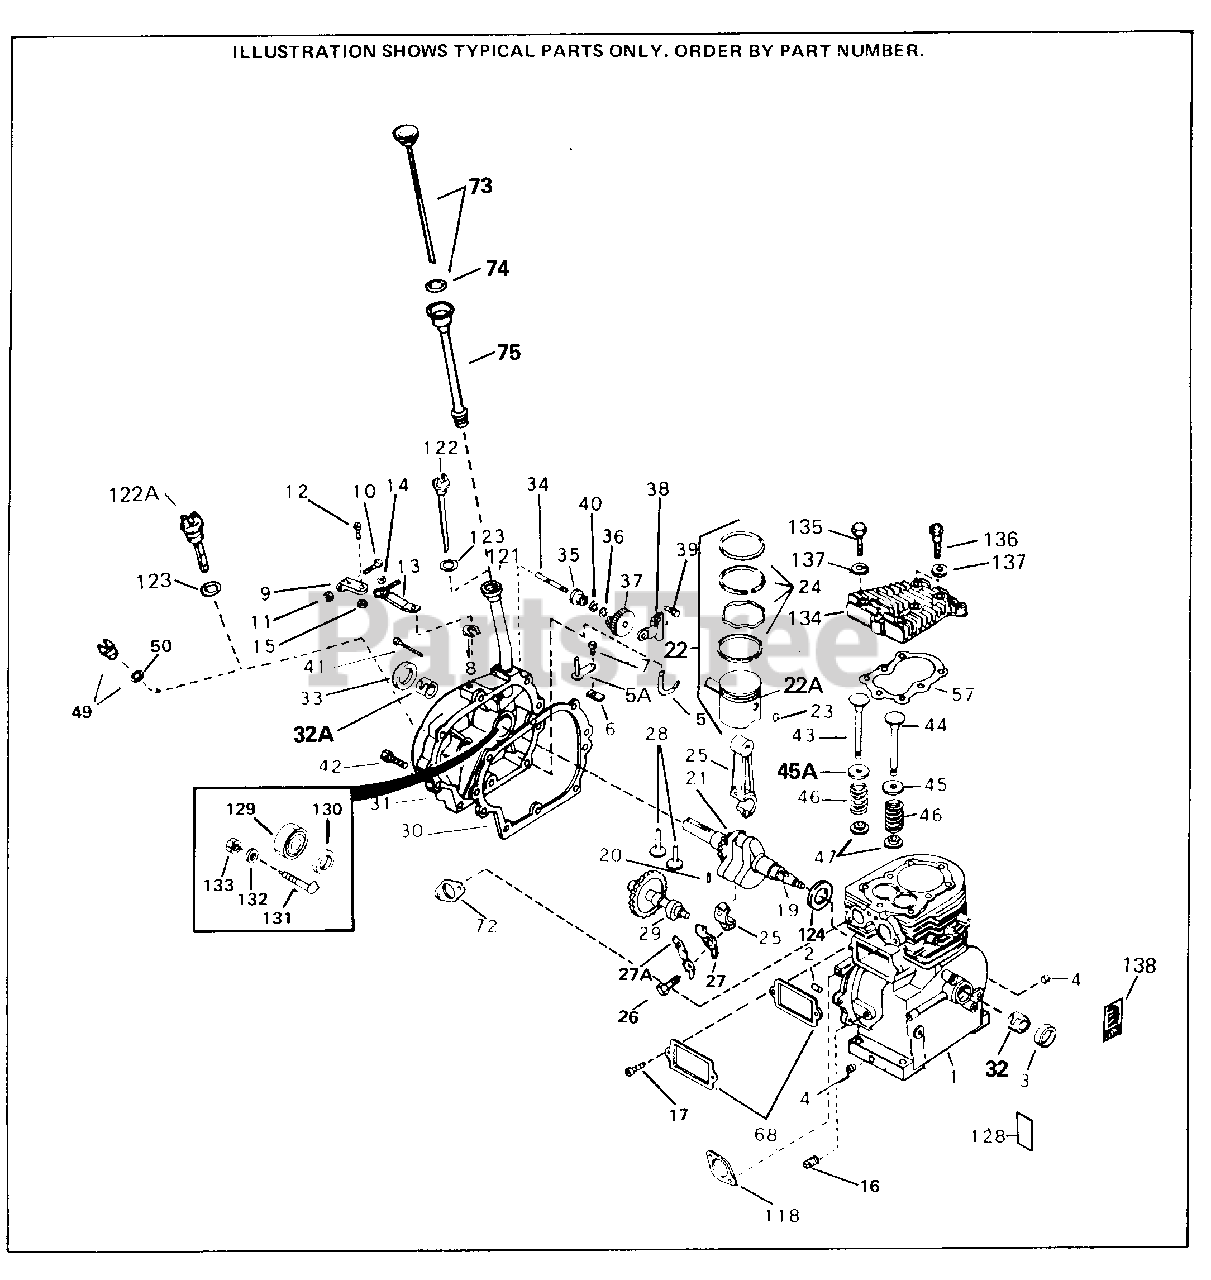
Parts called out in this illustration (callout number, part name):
1	"Cylinder (Incl. 2,3,4,16)(3-5/16") CI liner
2	Dowel Pin
3	Seal, Oil
4	Oil Drain Plug (Sq. hd., 1/4-18)
5	Rod Assy., Governor This one piece go vernor rod is no longer used. It is r eplaced by No. 30699C assy., Ref. 5A
5A	Rod Assy., Governor (Incl. 6 & 7)
6	Yoke, Governor
7	Screw, 6-40 x 5/16"
8	Retaining Ring
9	Governor Lever Clamp
10	Screw, 10-32 x 3/4"
11	Lock Nut, 10-32
12	Screw, 8-32 x 5/16"
13	Lever, Governor
14	Lock Washer #8
15	Lock Nut, 8-32
16	Plug, Pipe
17	Screw, 10-24 x 1/2" (Use as required)
19	Crankshaft
20	Pin, Crankshaft gear only)
21	Crankshaft Gear Early production onl y
22	Piston, Pin & Ring Set (Std.)
22	Piston, Pin & Ring Set (.010" OS)
22	Piston, Pin & Ring Set (.020" OS)
22A	Piston & Pin Ass'y. (Std.)(3-5/16") I ncl. 23
22A	Piston & Pin Ass'y. (.010" OS) Incl. 23
22A	Piston & Pin Ass'y. (.020" OS) Incl. 23
23	Piston Pin Retaining Ring
24	Ring Set (Std.) (3-5/16")
24	Ring Set (.010" OS)
24	Ring Set (.020" OS)
25	Rod Assy., Connecting (Incl. 26 & 27)
26	Bolt, Connecting rod (Incl. 2 pcs.)
27	Dipper, Oil
27A	Plate, Lock & Oil dipper This plate m ay be replaced by No. 34242 oil dippe r but No. 650662A screw must be used.
28	Lifter, Valve
29	Camshaft (MCR)
30	Gasket, Cylinder cover
31	Cover, Cylinder Incl. 32A, 33, 34, 4 9 & 50
32A	Bushing, Crankshaft
33	Seal, Oil
34	Shaft, Mechanical governor
35	Spool, Governor
36	Retaining Ring
37	Gear Assy., Governor (Incl. 40)
38	Bracket, Governor gear
39	Screw, 10-24 x 1/2"
40	Washer, Flat
41	Screw, 1/4-20 x 1-1/4" Use as requir ed
41	Screw, 1/4-20 x 1-3/16" Use as requir ed
42	Screw, 1/4-20 x 1-3/4" Use as requir ed
42	Screw, 1/4-20 x 1-11/16" Use as requi red
43	Intake Valve (Std.)
43	Intake Valve (Std.) (Incl. 47)
43	Intake Valve (1/32" OS) (Incl. 47)
44	Exhaust Valve (Std.)(Incl. 151)
44	Exhaust Valve (1/32" OS) (Incl. 151)
45	Valve Spring Cap
45A	Seal, Assy., Intake valve
46	Valve Spring
47	Cap, Lower valve spring
49	Oil Fill Plug (Incl. 312) also availa ble in Packaged Part #740079
50	Oil Fill Plug Gasket
57	Gasket, Cylinder head
68	Valve Cover Gasket
72	Intake Pipe Gasket
118	Gasket, Exhaust (Use as required)
122	Dipstick (Incl. 123)
123	Oil Fill Plug Gasket
128	Decal, Instruction
134	Head, Cylinder (Use as required)
135	Screw, 5/16-18 x 1-1/2" Use as requir ed, but do notuse 650691 washer
135	Screw, 5/16-18 x 1-5/8" Can use 6021A , but discard 650691 washer
136	Screw, 5/16-18 x 1-3/4" Use as requir ed
137	Washer (Do Not Use with 6021A screw)
138	Decal, Name
